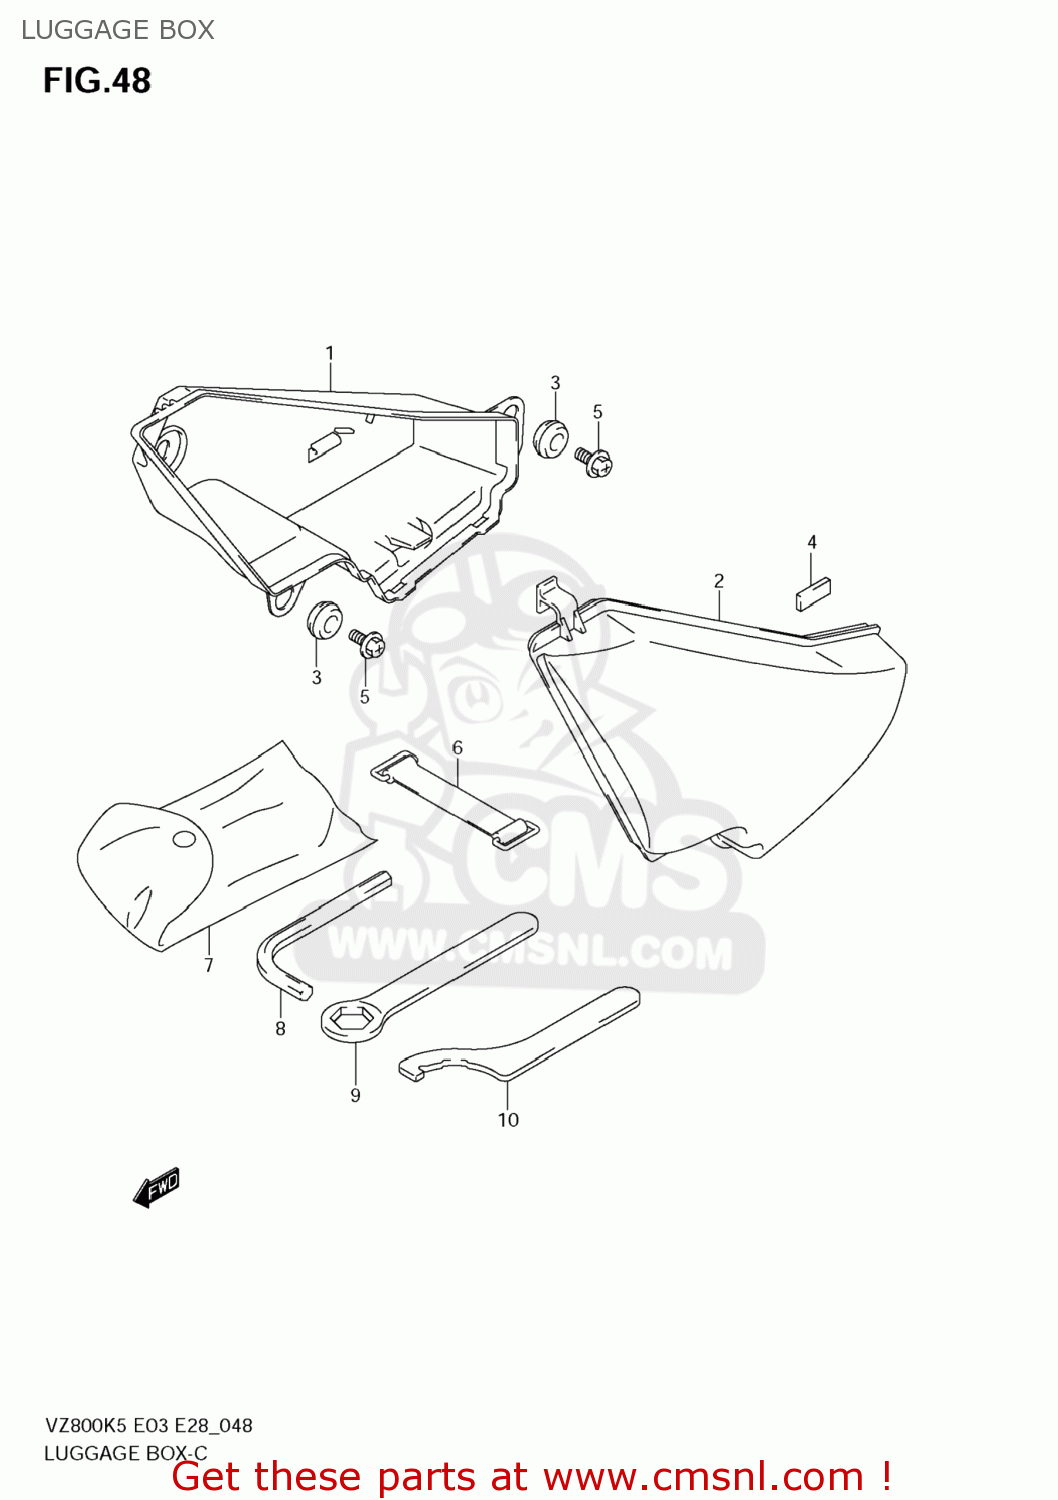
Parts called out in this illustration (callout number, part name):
1	BODY,LUGGAGE BOX
2	LID,LUGGAGE BOX
3	PROTECTOR,BATTERY
4	CUSHION,LUGGAGE BOX NO.2
5	BOLT
6	O RING(D:3.5,ID:61)
7	TOOL ASSY
8	HEXAGON SPANNER,8
9	RING SPANNER(22)
10	CLAMP
